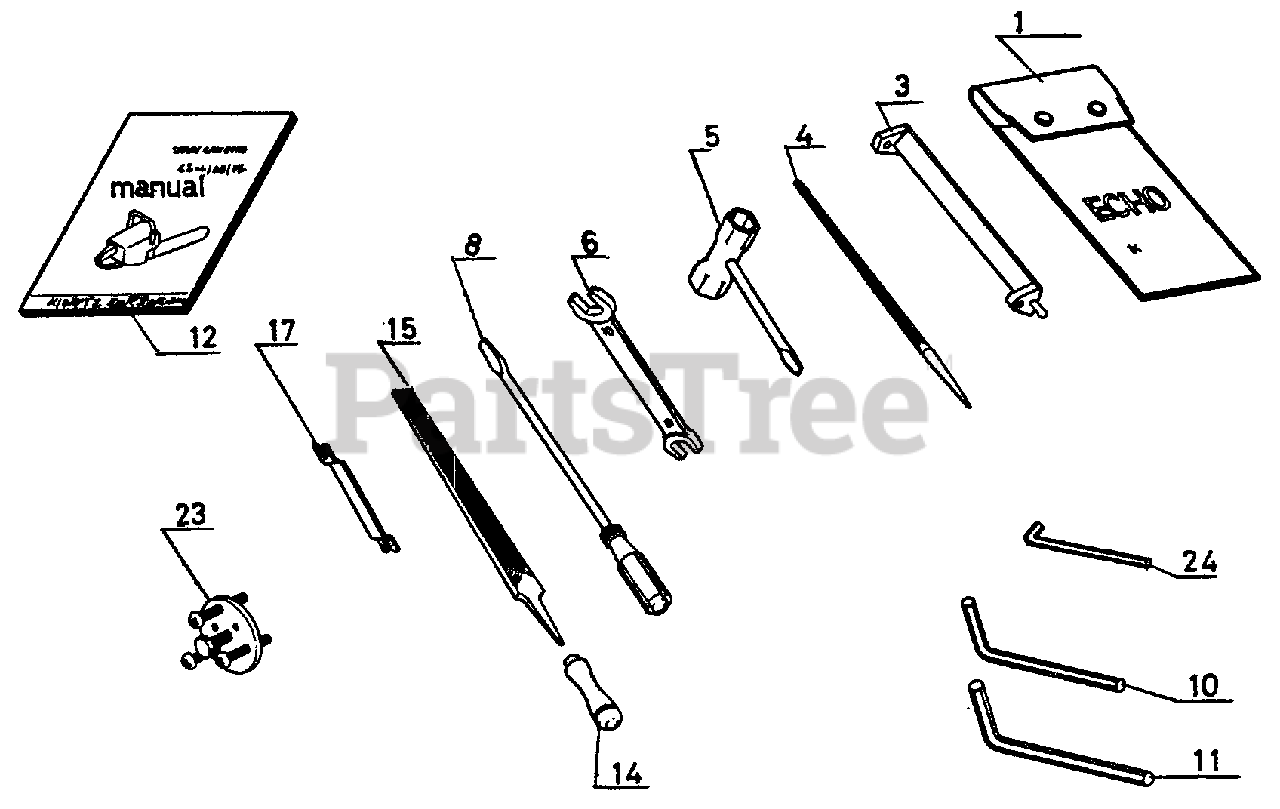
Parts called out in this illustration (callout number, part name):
1	BAG, TOOL
3	FILE HOLDER
4	FILE - ROUND
5	T-WRENCH - 17X19mm
6	SPANNER - 8X10mm
8	SCREWDRIVER
10	HEX KEY - 4mm
11	HEX KEY - 5mm
12	OWNER'S MANUAL
14	FILE GRIP
15	FILE - FLAT
17	DEPTH GAUGE
23	PULLER
24	HEX KEY - 3mm
